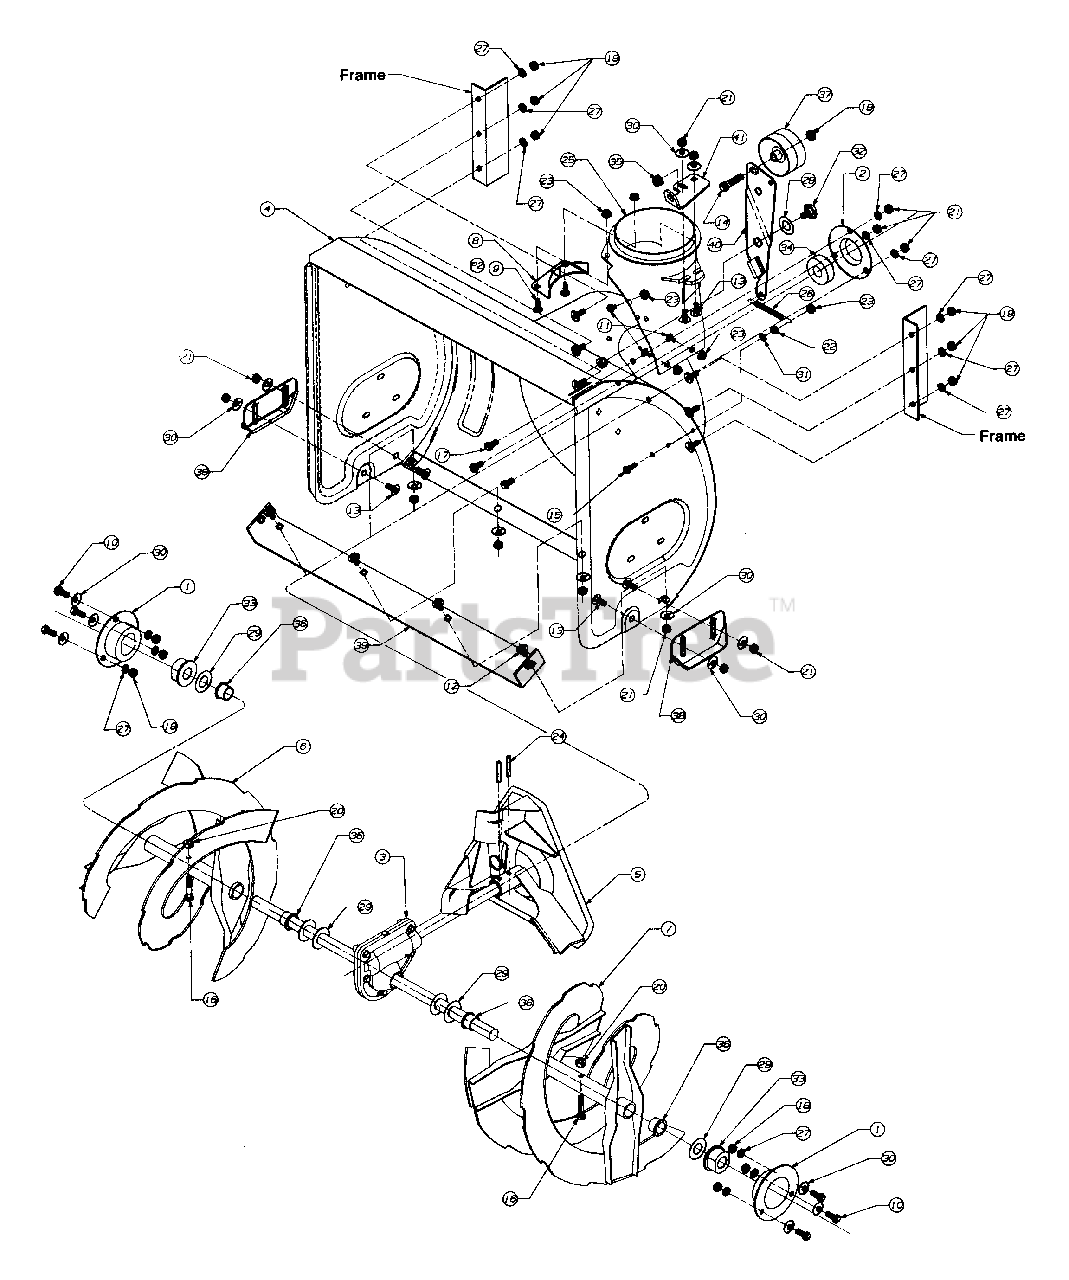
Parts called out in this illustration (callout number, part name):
2	Housing, Bearing
3	Gear Assembly (22" Auger)
3	Gear Assembly (24" Auger)
3	Gear Assembly (26" Auger)
3	Gear Assembly (28" Auger)
6	Spiral, 28" R.H.
7	Spiral, 26" L.H.
7	Spiral, 28" L.H.
9	Bolt, Carriage
10	Screw, Hex
11	Screw, Carriage
12	Carraige Bolt
13	Screw, Carriage
14	Screw, Hex
15	Screw, Hex
16	Bolt, Shear
17	Screw, Hex
18	Hex Lock Nut
19	Hex Nut
20	Nut, Hex Lock
21	Nut, Hex
22	Hex Nut
23	Nut, Lock, Hex, Flanged
24	Spring Pin
25	Adapter, Chute
26	Spring
27	Lock Washer
28	Washer, Flat
29	Washer, Flat, .71 I.D. x 1.49 O.D. x .06
30	Washer, Bell
31	Washer, Lock
32	Screw, Shoulder
33	Bearing, Flange
34	Bearing, Ball
35	Bushing, Plastic
36	Bushing, Flange
37	Idler, Flat
38	Slide Shoe, Standard Steel
38	Skid Shoe Kit, Standard Polymer
